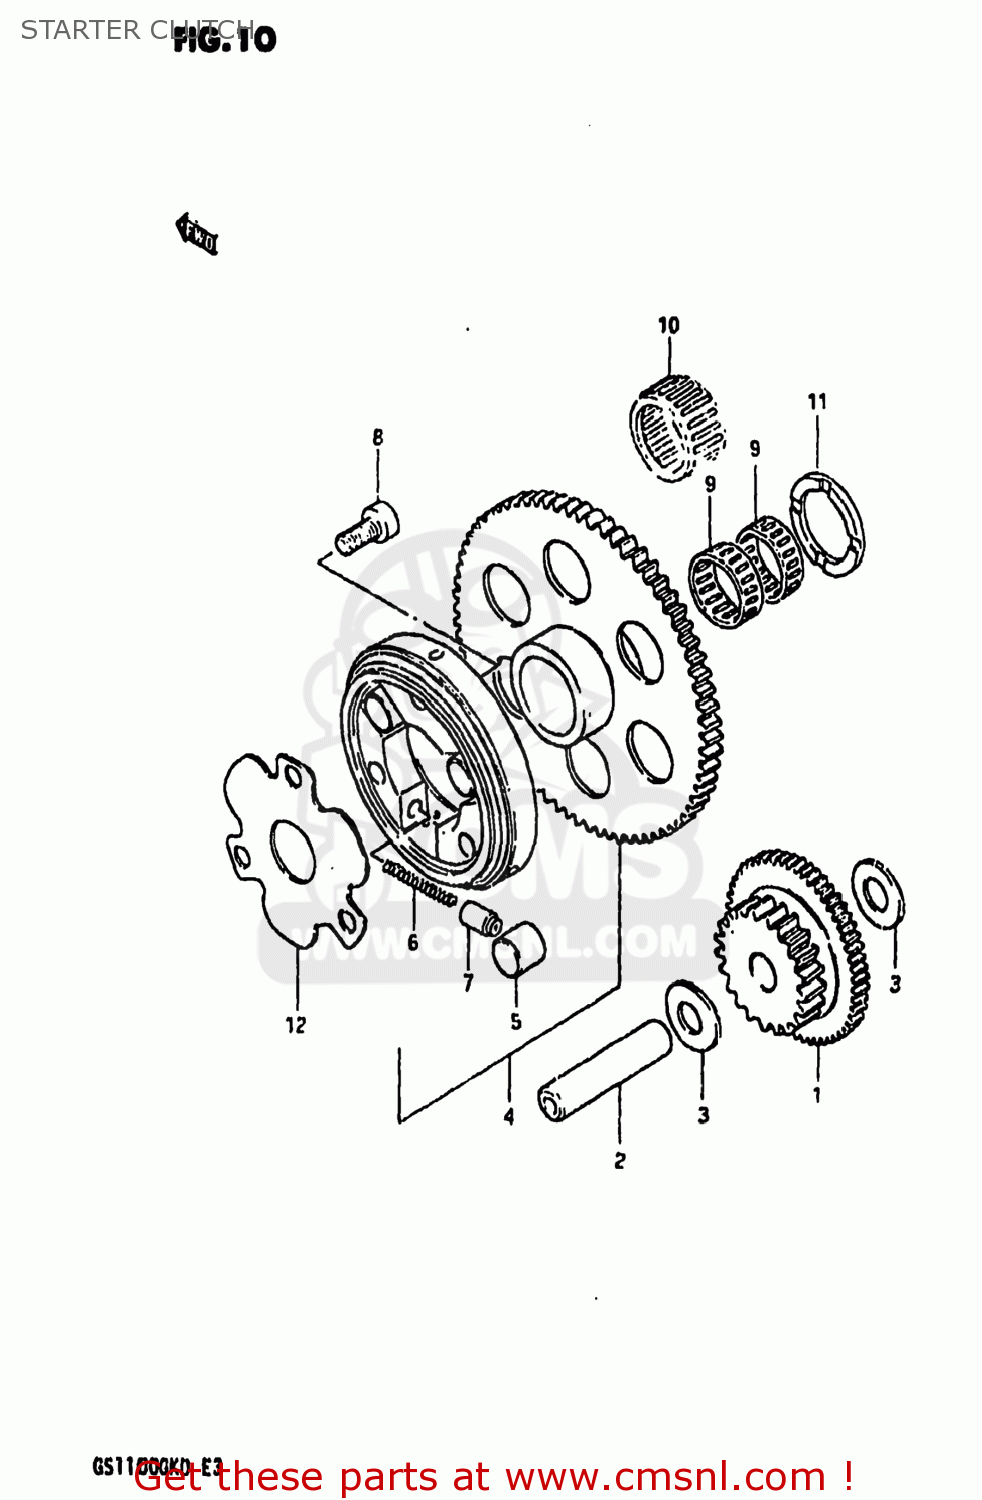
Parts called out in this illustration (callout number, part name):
1	GEAR,STARTER IDLE
2	PIN(7.4X13X56)
3	WASHER(13.3X25X0.85)
4	CLUTCH SET,STARTER
5	PIN(14X13)
6	SPRING
7	PIECE,PUSH
8	BOLT
9	BEARING
10	ROLLER BEARING (25X31X2
11	WASHER(25X38X2.5)
12	SHIM,STARTER CLUTCH HUB
